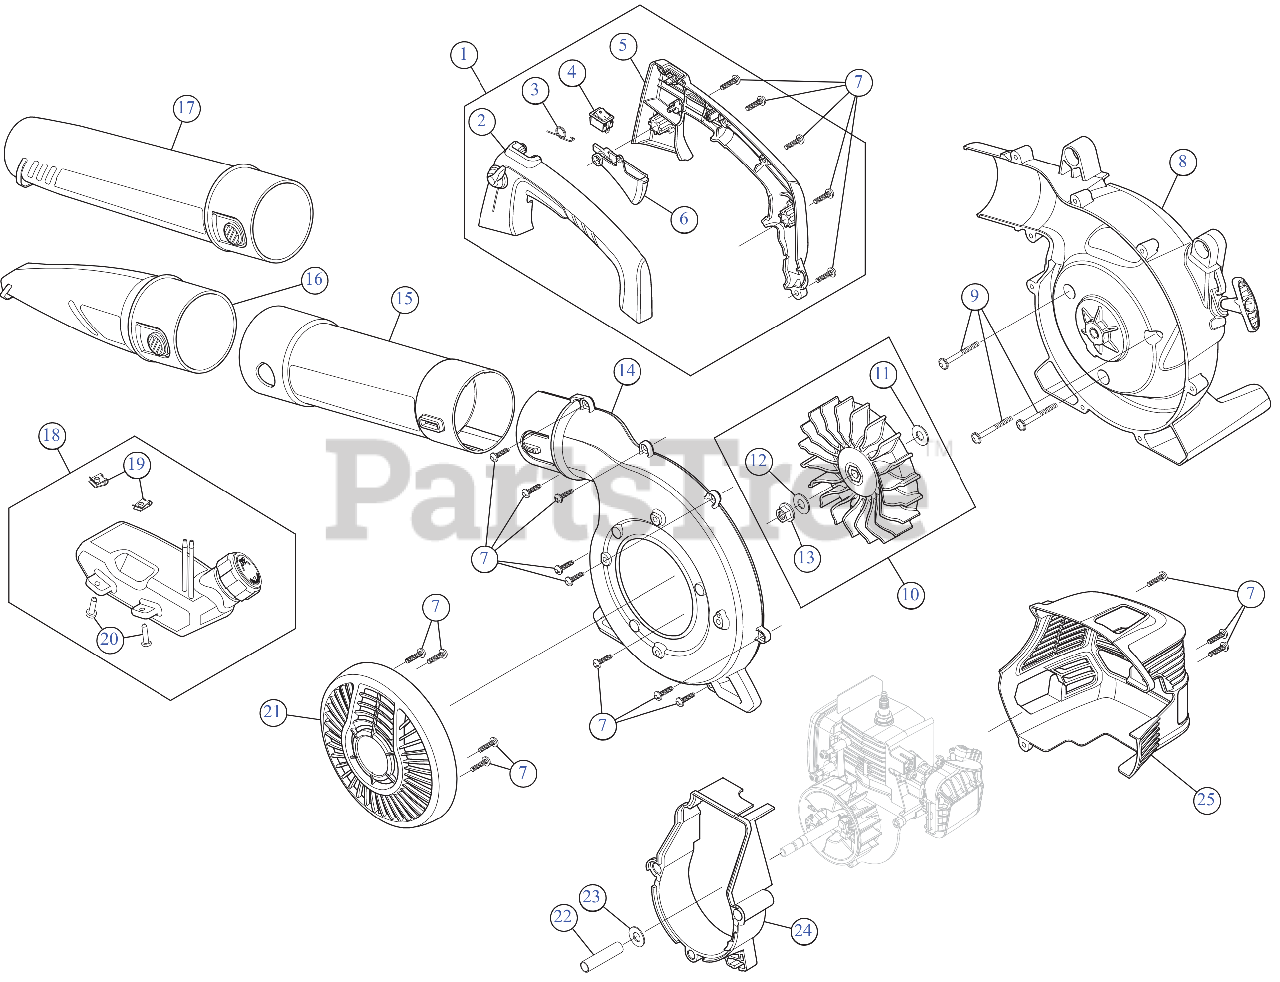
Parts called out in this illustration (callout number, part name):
1	HANDLE ASSEMBLY
2	HANDLE (LH)
3	SPRING TRIG
4	MOMENTARY SWITCH ON/OFF
5	HANDLE (RH)
6	THROTTLE TRIGGER
7	SCREW 8-16 x 3/4
8	IMPELLER HOUSING ASSEMBLY (INNER)
9	SCREW 10/32
10	IMPELLER ASSEMBLY
11	FLAT WASHER
12	LOCK WASHER
13	NUT 3/8-24
14	IMPELLER HOUSING ASSEMBLY (OUTER)
15	TUBE UPPER
16	NOZZLE
17	TUBE LOWER
18	FUEL TANK ASSEMBLY
19	NUT, TINNERMAN U-T
20	SCREW:10-6 x .75
21	INTAKE COVER
22	SPACER
23	FLAT WASHER
24	ENGINE ADAPTER
25	ENGINE COVER
